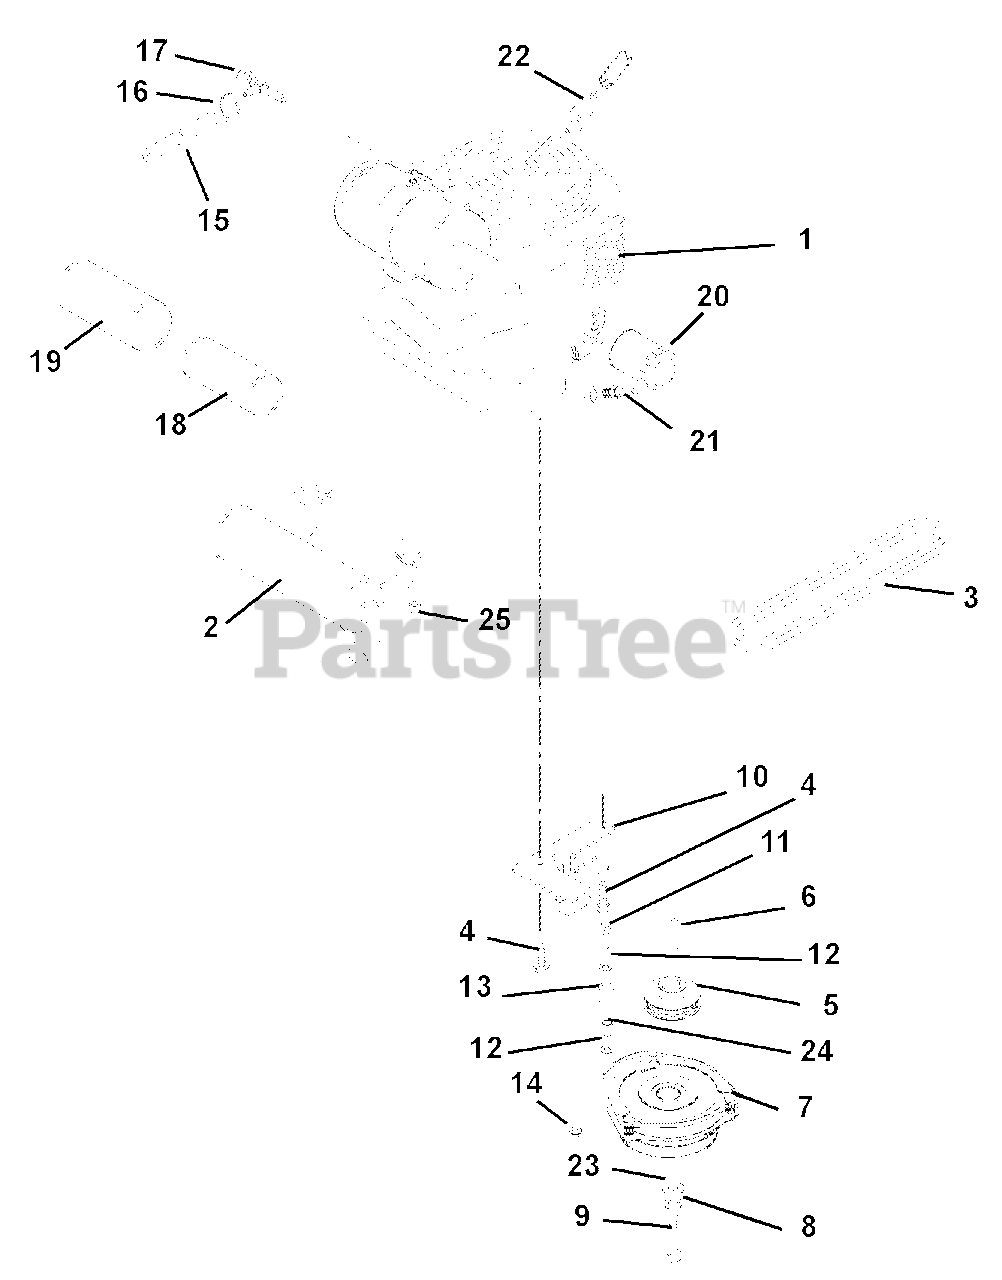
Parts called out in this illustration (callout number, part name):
1	Engine, Kawasaki (FX751V) (992210, 212)
2	Muffler, Kawasaki Vertical
3	Belt, Poly-V
4	Bolt, Hex .38-16 x 1.25 FTH G5 EP30
5	Sheave, Poly V 1.127 x 3.275
6	Key, Square .25 x 3.50 x .25 SA
7	Clutch, Electric
8	Washer, Locking .44 x .109
9	Bolt, Hex .44-20 x 1.50 Grade 5 YZ EP80
10	Anchor, Clutch
11	Bolt-Hex .38-16 x 1.50 Grade 5
12	Washer-Flat-Steel .406 x .812 x .065
13	Bumper, Rubber .62 x 1.0 x .88 LG
14	Nut, Locking-Top-Flange .38-16
15	Gas Line, Bulk .25 I.D.
16	Cable Tie LG 5-1/2
17	Drain, 1/2" Drain
18	Element, Inner Safety
19	Element, Outer Primary
20	Oil Filter
21	Spark Plug
22	Fuel Filter
23	Washer, Flat Steel .469 x 2 x .25
24	Bushing, .407 x .625 x .813
25	Nut, Locking, Top M8-1.25
